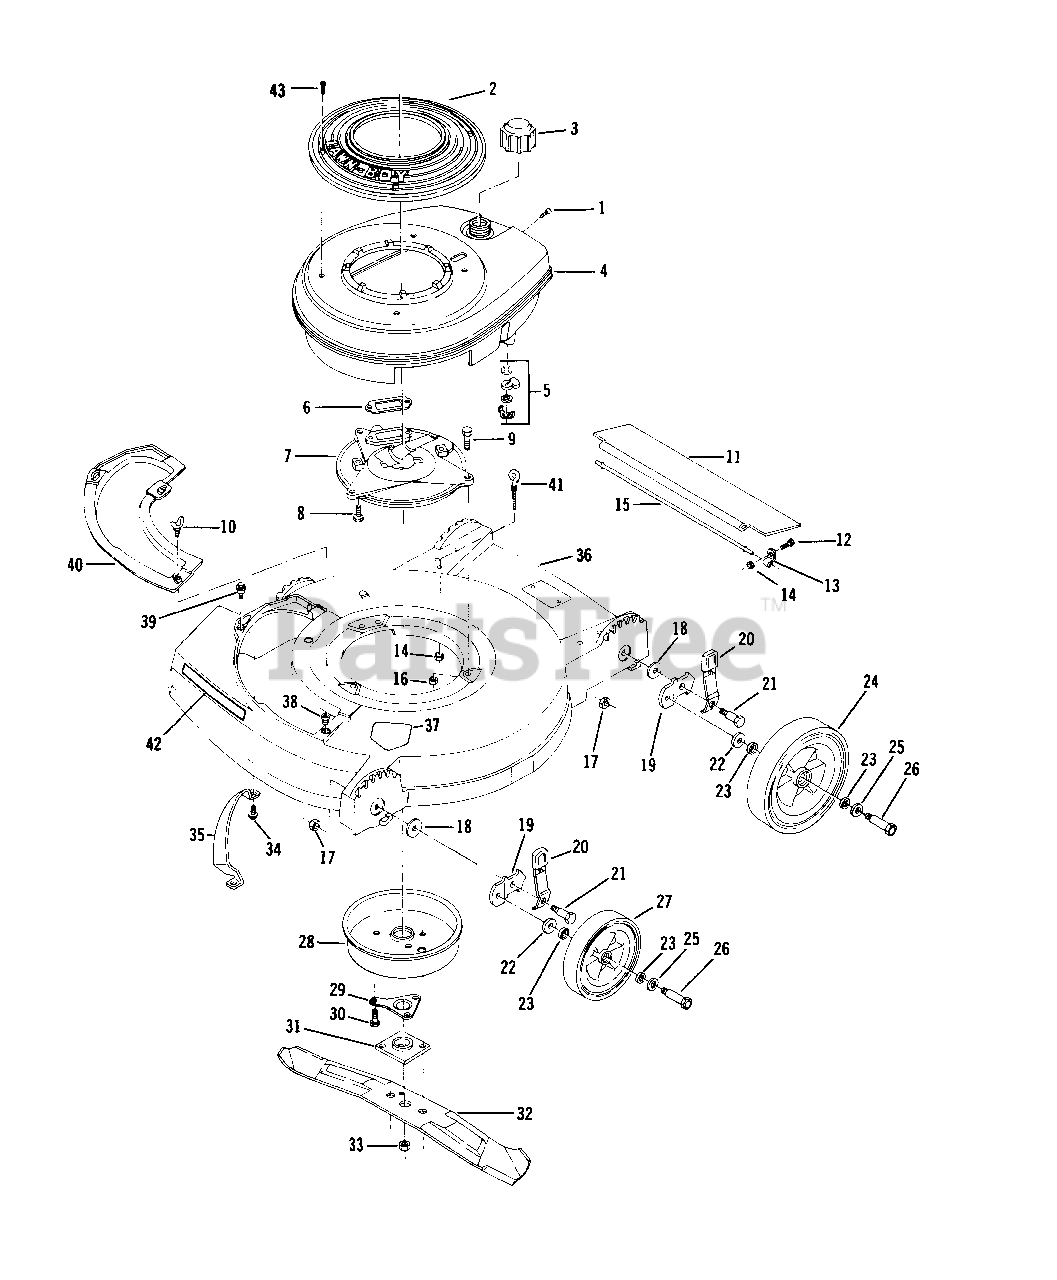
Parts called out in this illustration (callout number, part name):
1	Screw
2	Cover-Shroud
3	Fuel Cap
4	Shroud-Engine
5	Fuel Shut-Off Assembly
6	Gasket-Exhaust
7	Plate-Muffler
8	Screw-Muffler Plt. to Block
9	Screw-Muffler Plt. to Hsg.
10	Wing Screw
11	Shield-Trailing
12	Screw-Trailing Shield
13	Clamp
14	Nut
15	Rod-Trailing Shield
16	Nut-Muffler Plt. to Hsg.
17	Nut-Wheel Ht. Adjust
18	Washer-Wheel Ht. Adjust
19	Bracket-Wheel Ht. Adjust
20	Knob and Spring Assembly
21	Bolt-Shoulder
22	Washer
23	Washer-Felt
24	Wheel-Rear
25	Washer-Wheel Bolt
26	Bolt-Wheel
27	Wheel-Front
28	Muffler Cover Assembly
29	Support-Crankshaft
30	Screw-Muff. to Muff. Plate
31	Collar and Plate Assembly
32	Blade 19"
33	Nut
34	Screw
35	Toe Bar
36	Housing Assembly
37	Decal-Blade Contact Warning
38	Grommet
39	Screw-Plate Mounting
40	Cover Plate
41	Eyelet
42	Decal-Headliner
43	Screw-Shroud
